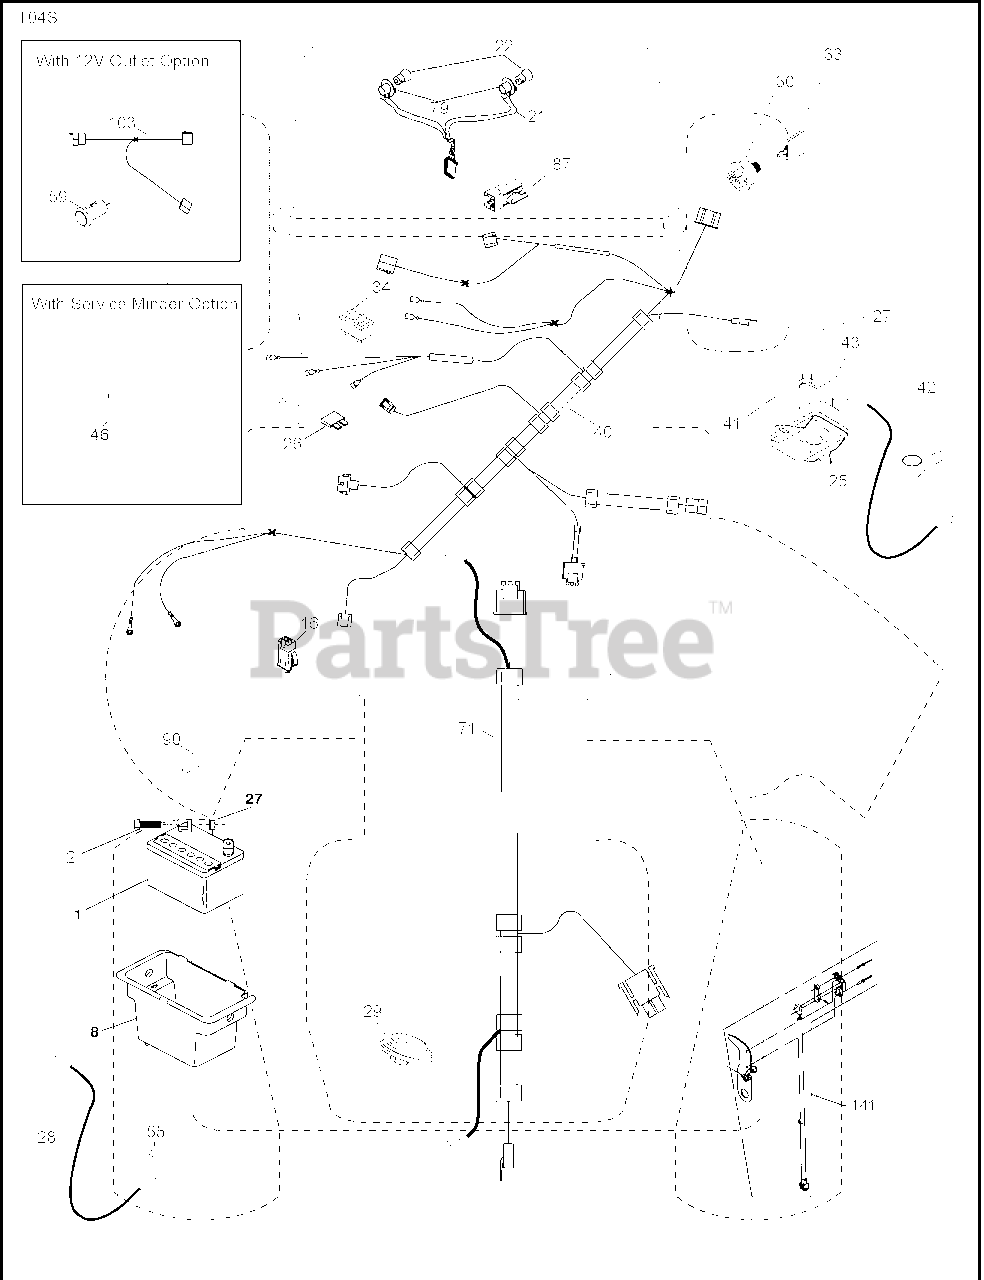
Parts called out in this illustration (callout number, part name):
1	Battery
2	Bolt Hex Head 1/4-20 x 3/4
8	Box Battery
16	Switch Interlock Push-In
21	Harness Socket Light w/4152J
22	Bulb Light
25	Cable Starter
26	Fuse
27	Nut Keps Hex 1/4-20 unc
28	Cable, Ground
29	Switch, Seat
30	Switch, Ignition
33	Key/Chain
34	Switch Light/Reset
40	Harness Ignition Dash
41	Screw Thd Cut 1/4-20 x 1/2
42	Cover, Terminal
43	Solenoid
46	Gauge SRVCMNDR HRMTR
55	Screw Thdrol 5/16-18 x 3/4 TYTT
71	Harness Ignition
79	Socket Asm Bulb Twistlock
87	Switch Interlock Clutch Cable
90	Cover Terminal Battery
141	Kit T2 ROS
